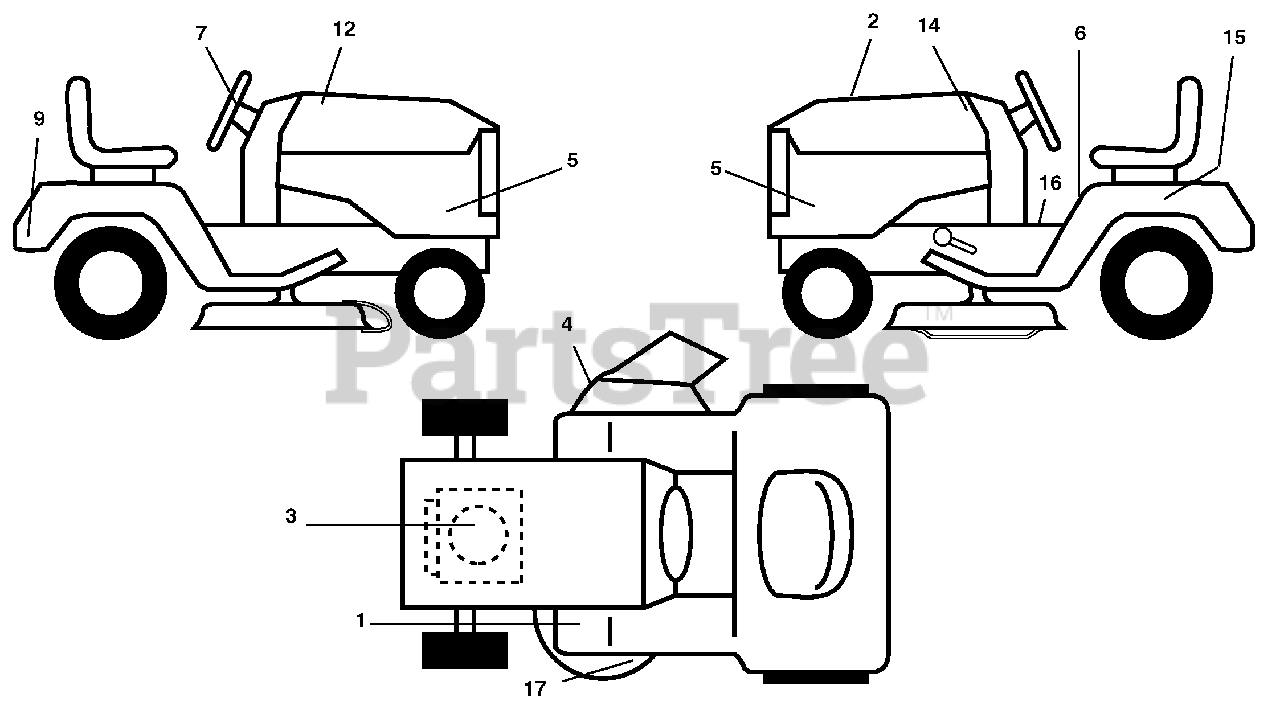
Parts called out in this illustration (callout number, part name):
1	Decal, Clutch Brake
2	Decal, Replacement
3	Decal, Engine HP
4	Decal Warning
5	Decal, SDPNL
6	Decal, Fender Danger English
7	Decal Ins Str Wh
9	Decal Fender
12	Decal, Hood RH
14	Decal, Hood LH
15	Decal, Caution, Battery
16	Decal, Oper Sdl P/L Gear Dr Eng
17	Decal, V-Belt Sch.
17	Decal, Handle Lft Height Adj.
17	Manual, Operator's E&F
17	Manual, Parts E&F
